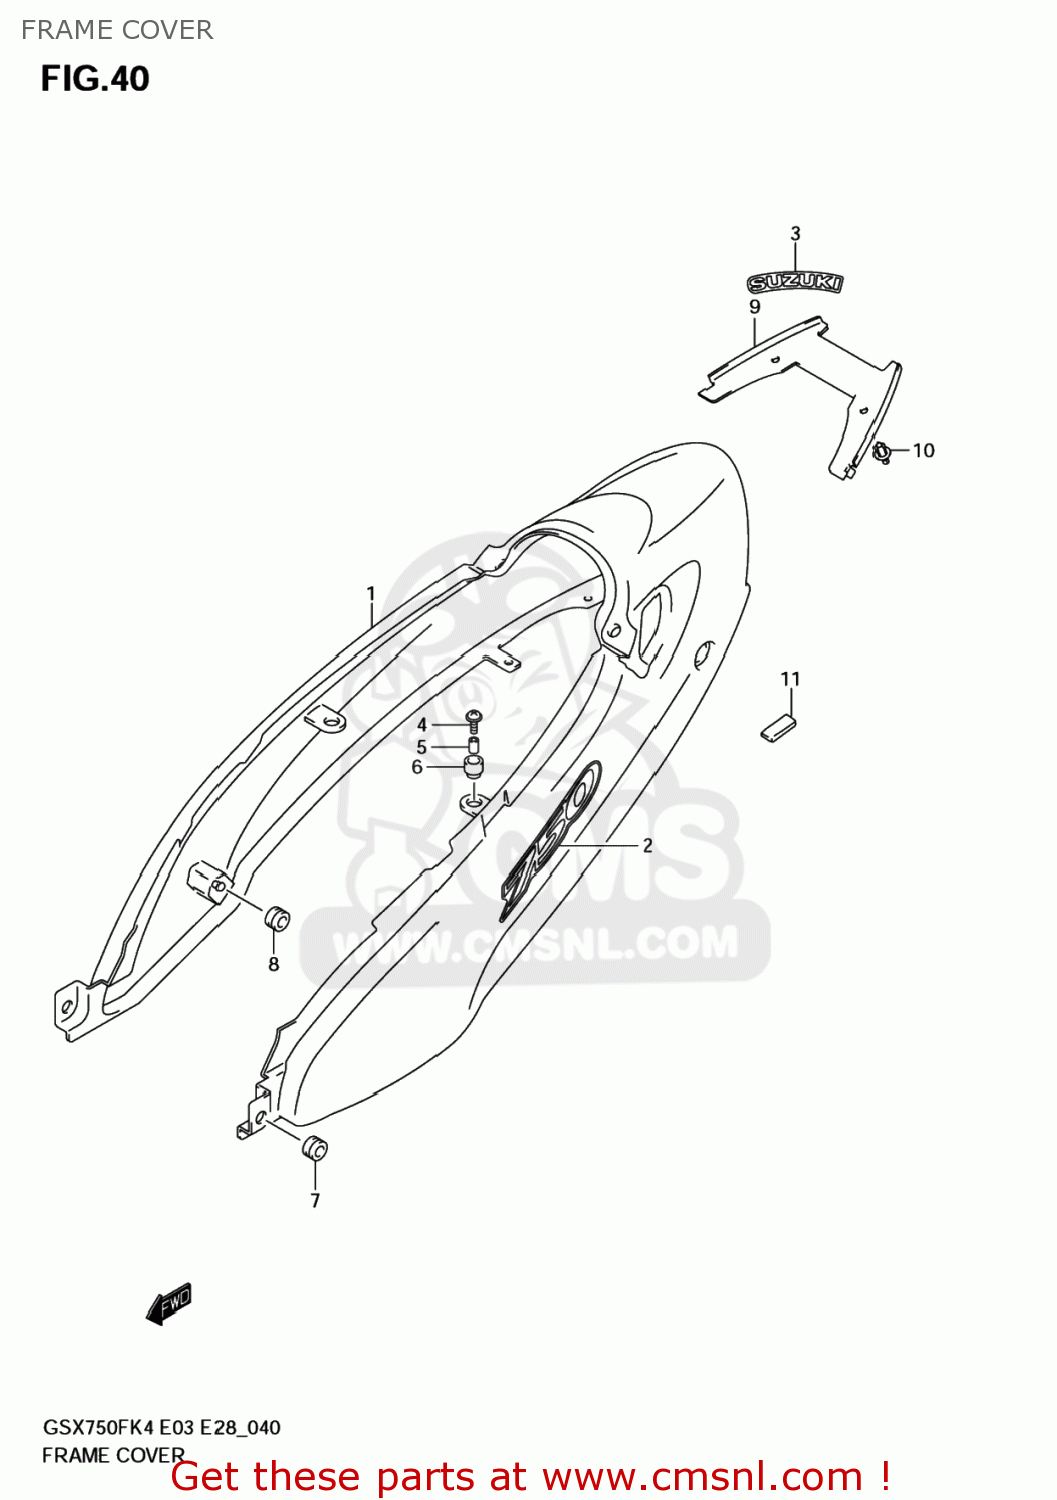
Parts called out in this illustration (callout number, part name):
1	COVER,FRAME(GRAY)
2	EMBLEM,FRAME COVER
3	EMBLEM,FRAME COVER
4	SCREW(6X20)
5	SPACER(6.5X10X9.4)
6	CUSHION
7	CUSHION
8	CUSHION
9	COVER,FRAME LWR
10	CLIP(BLACK)
11	CUSHION
